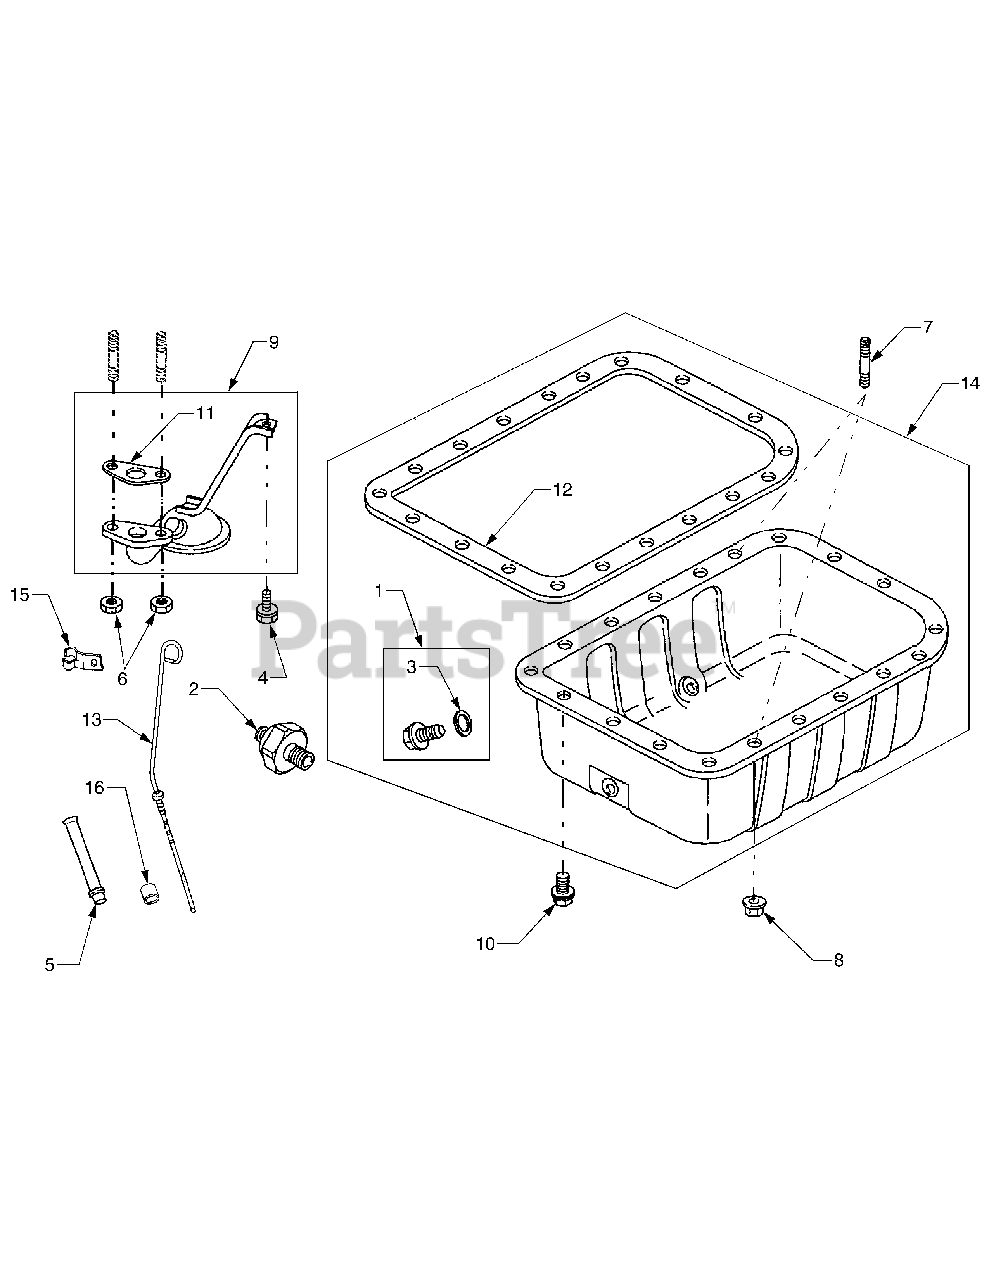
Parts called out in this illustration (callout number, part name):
1	Plug, Oil Drain 16mm
2	Switch, Oil Pressure
3	Washer, Sealing
4	Screw, Oil Pump Screen
5	Tube, Dipstick
6	Nut, Oil Pump Screen
7	Stud, Oil Pan
8	Nut, Oil Pan
9	Oil Pump Screen
10	Screw, Oil Pan
11	Gasket, Oil Pump Screen
12	Gasket, Oil Pan
14	Pan, Oil
15	Bracket, Support
16	Collar, Dipstick Tube
